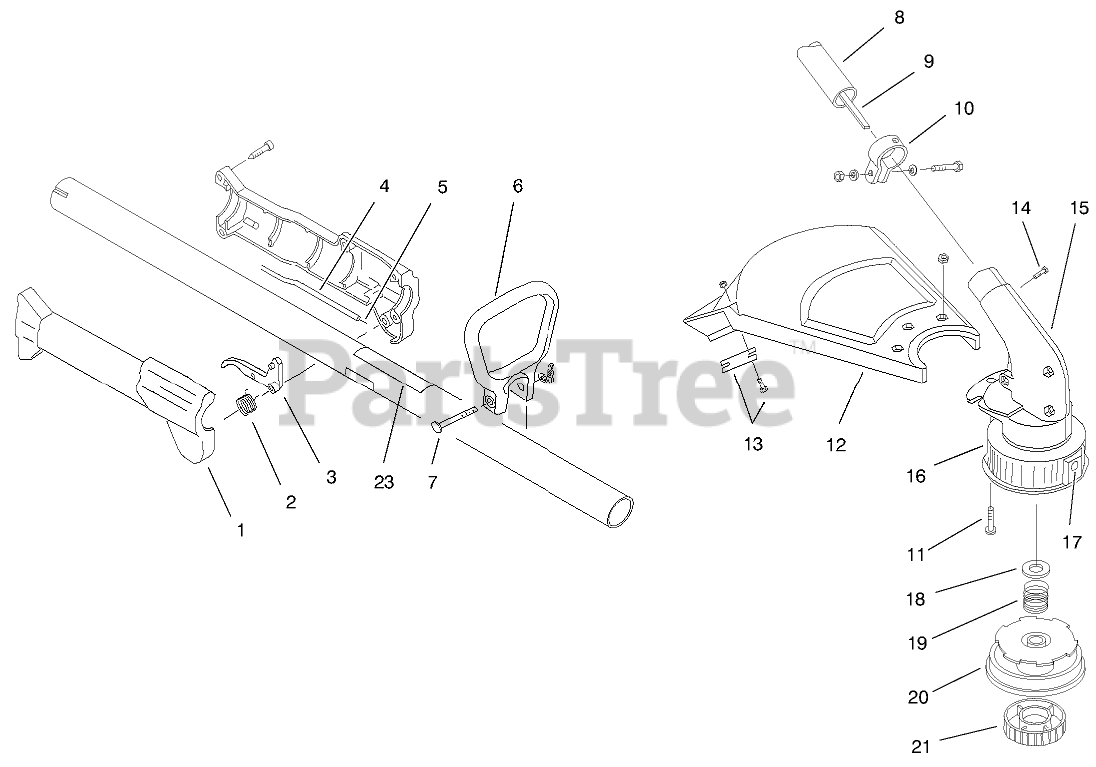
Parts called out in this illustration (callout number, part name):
1	Throttle Housing & Trigger Asm.
2	SPRING - TRIGGER
3	HSG - THROTTLE TRIGGER
4	Throttle Cable Housing
5	Throttle Cable
6	D-Handle
7	HARDWARE - D-HANDLE
8	Drive Shaft Housing Asm.
9	SHAFT - FLEX, 48.94
10	CLAMP ASM - UPPER
11	ASM - GUARD MTG SCREW
12	Guard and Blade Asm.
13	BLADE ASM
14	Anti-Rotation Screw
15	Gearbox Asm.
16	OUTER SPOOL EYELET ASM
17	EYELET
18	RETAINER WASHER(SET OF 10)
19	SPRING
20	REEL - INNER
21	SMALL BUMP KNOB ASM
23	DECAL - SAFETY SYMBOLS
